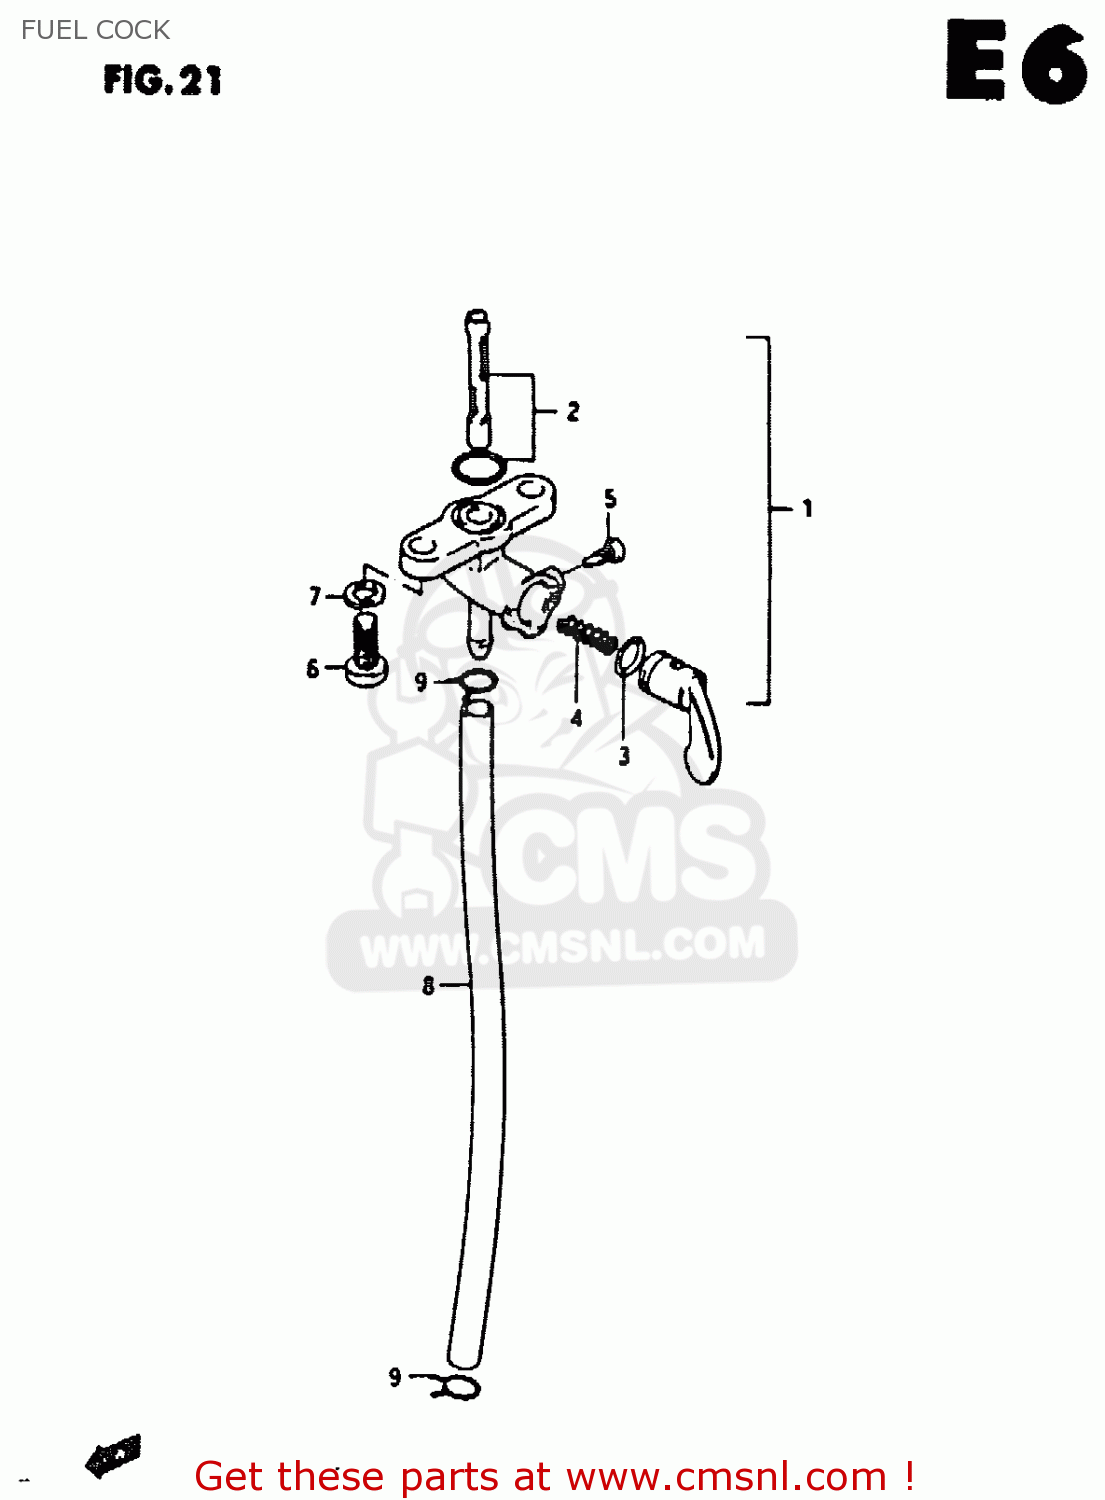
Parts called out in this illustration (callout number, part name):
1	COCK ASSY,FUEL
2	FILTER SET FUEL
3	O RING,LEVER
4	SPRING,FUEL COCK VALUE
5	SCREW
6	SCREW
7	WASHER,LOCK
8	HOSE
9	CLIP
